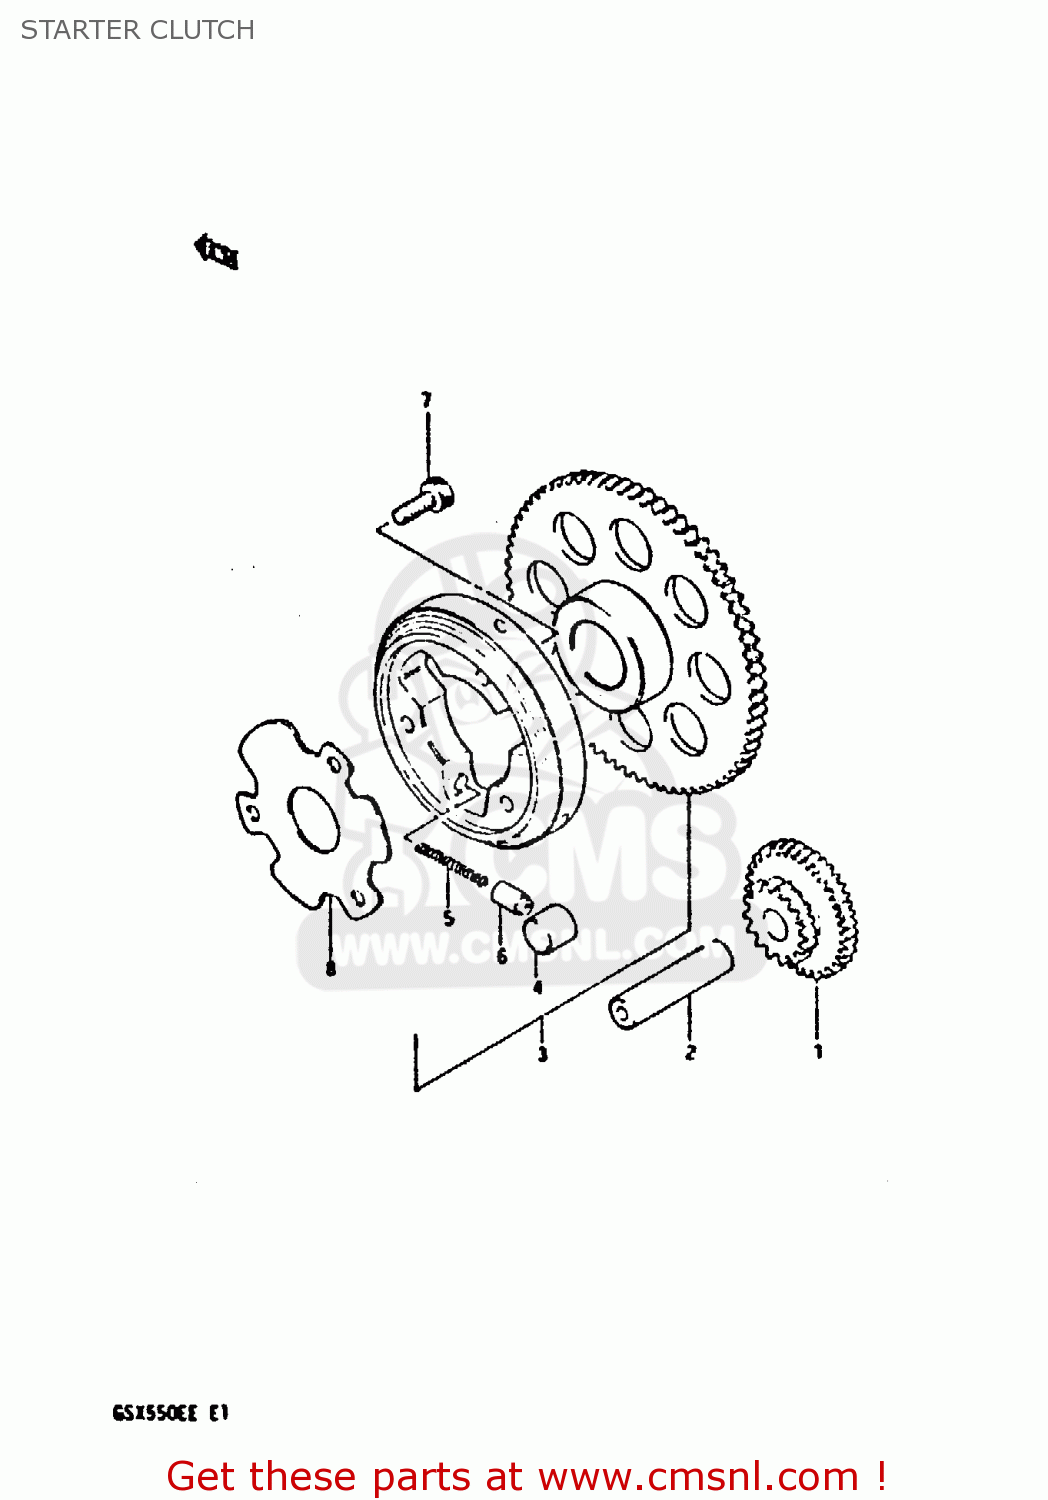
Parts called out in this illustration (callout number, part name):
1	GEAR,STARTER IDLE
2	PIN(7.4X13X56)
3	CLUTCH SET,STARTER
4	PIN(14X13)
5	SPRING
6	PIECE,PUSH
7	BOLT
8	SHIM,STARTER CLUTCH HUB
